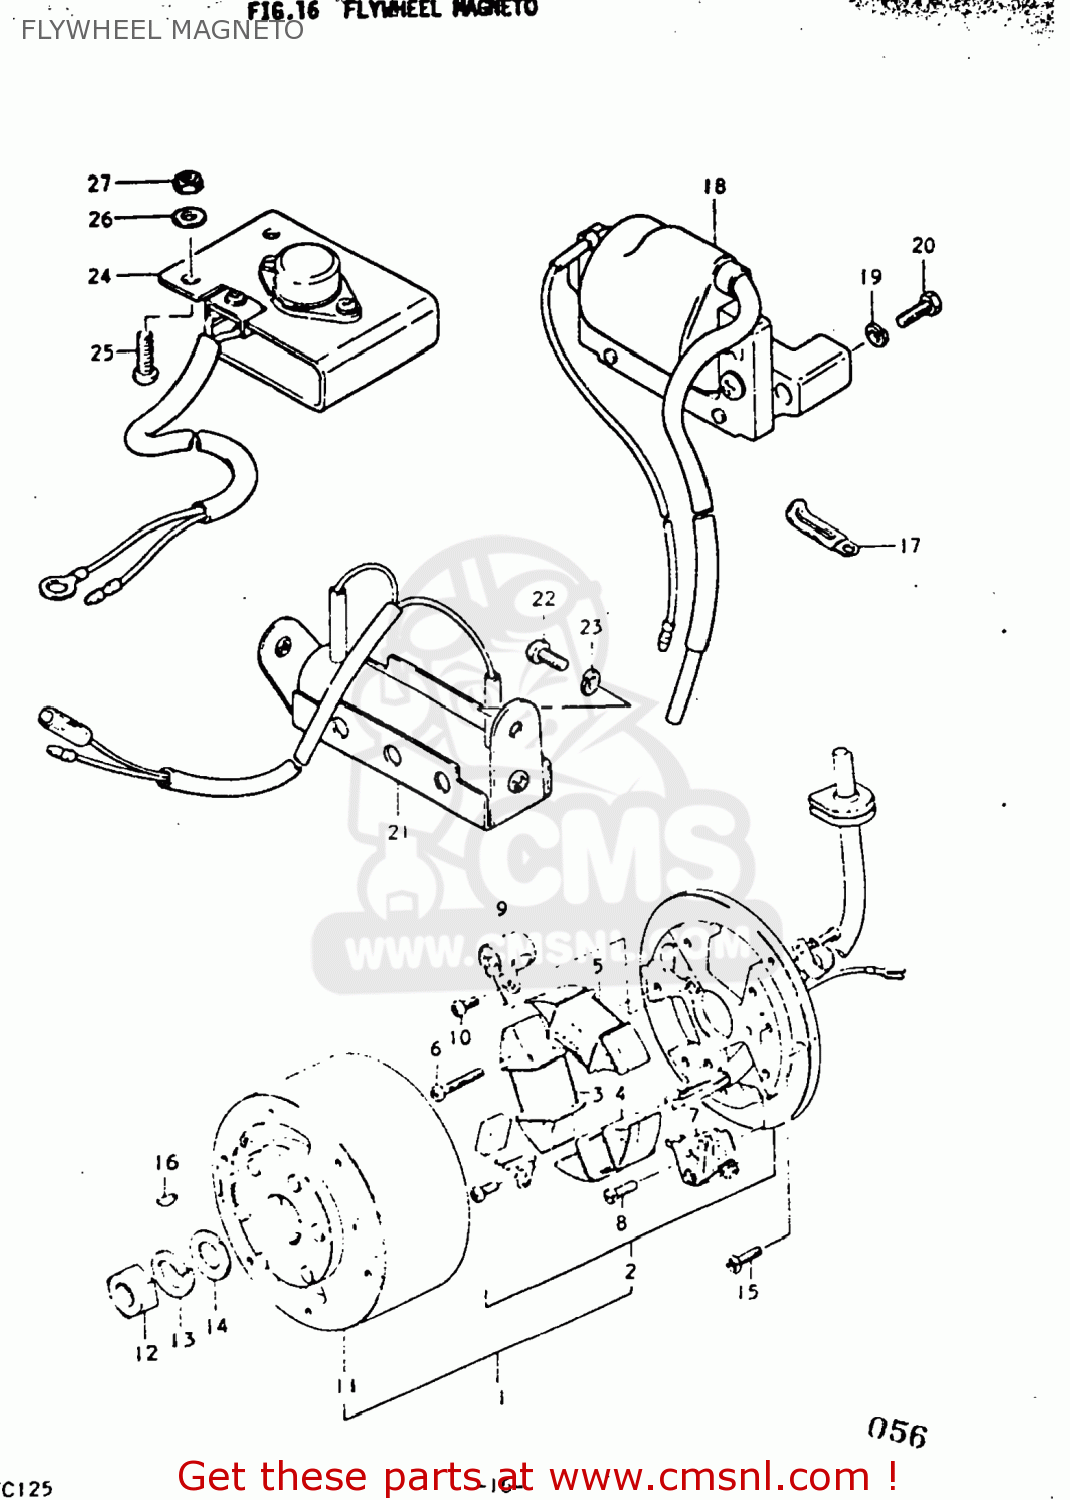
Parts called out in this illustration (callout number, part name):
1	MAGNETO ASSEMBLY
2	STATOR ASSEMBLY
3	COIL,LIGHTING
4	COIL,LIGHTING
5	COIL,PRIMARY
6	SCREW
7	POINT ASSEMBLY,CONTACT
8	.SCREW
9	CONDENSER
10	SCREW
11	ROTOR ASSEMBLY
12	NUT (10MM)
13	LOCK WASHER
14	WASHER
15	SCREW
16	KEY
17	CLAMP
18	COIL ASSEMBLY,IGNITION
19	LOCK WASHER
20	BOLT
21	MAGNETO RESISTOR
22	SCREW
23	LOCK WASHER
24	REGULATOR ASSEMBLY
25	SCREW 6X12
26	WASHER
27	NUT
